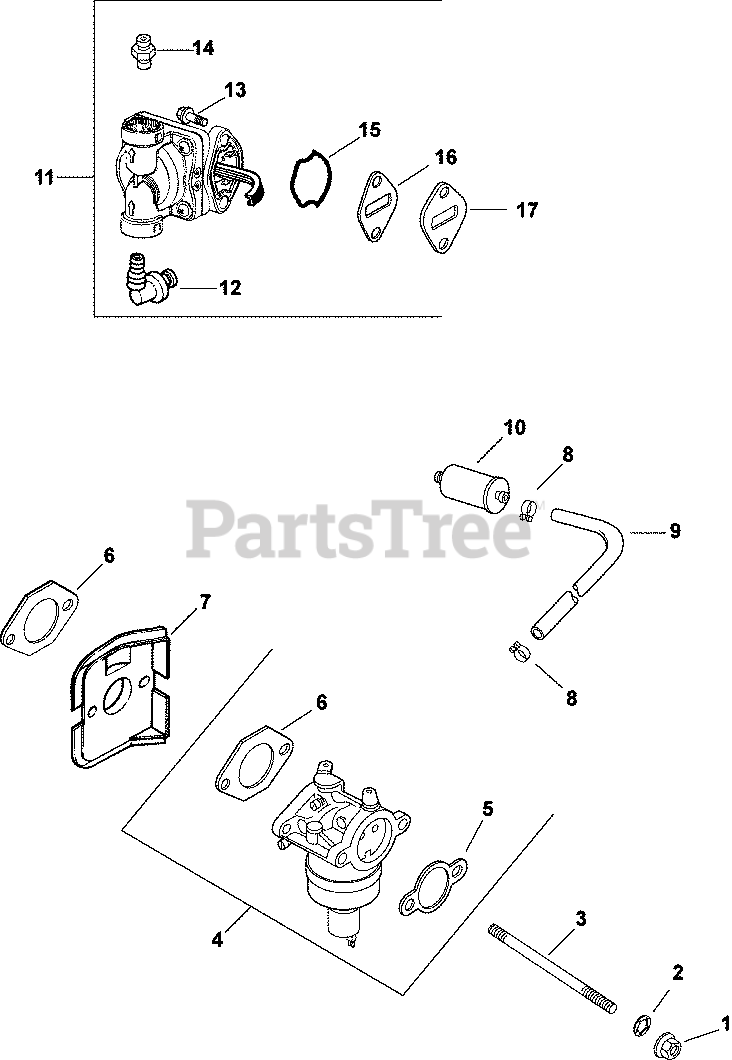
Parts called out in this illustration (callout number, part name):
1	NUT, FLG M6X1.0
2	WASHER, INT TOOTH LOCK 1/4"
3	STUD,M6X1.0X116
4	KIT, CARBURETOR W/GASKETS
5	GASKET, AIR CLEANER BASE
6	GASKET, CARBURETOR
7	DEFLECTOR, HEAT
8	CLAMP, HOSE (KM)-USE 25 237 31-S
9	HOSE,LW PERM.FUEL 24.00"-USE 25 111 81-S
10	FILTR,FUEL 75 MICRON (GRAVTY FEED)
NI	KIT, HIGH ALTITUDE (+10,000 FT)
NI	KIT, REPAIR FLOAT
NI	KIT, CHOKE REPAIR
NI	KIT, REPAIR SOLENOID
NI	KIT, REPAIR CARB (PUMP FEED)
